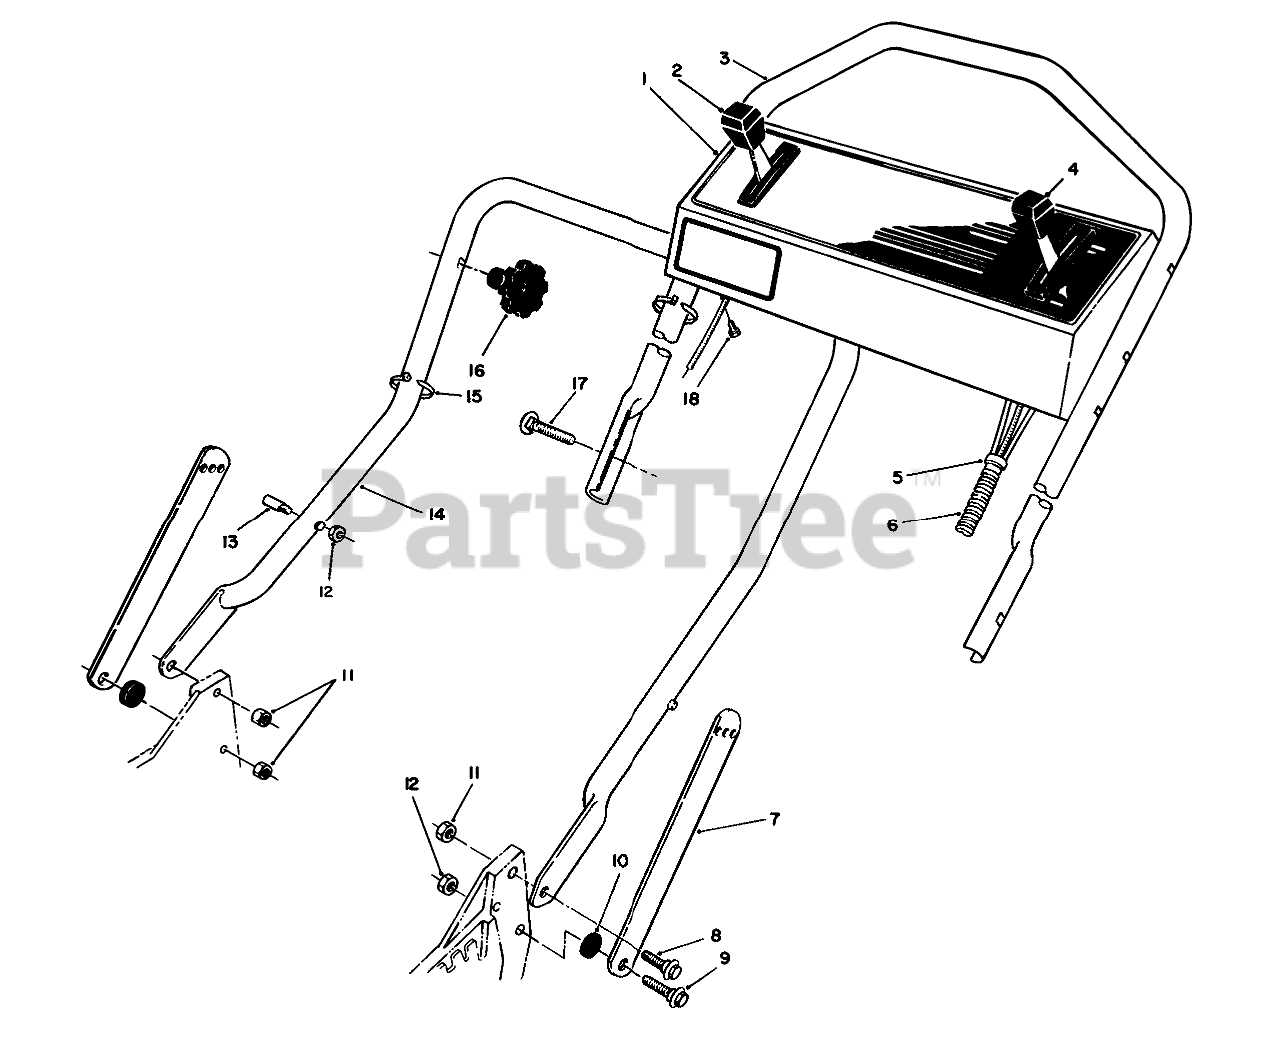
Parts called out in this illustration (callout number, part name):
1	SILK SCRN CONTROL PANEL
2	GROUND SPEED CONTROL
3	Handle-Upper
4	THROTTLE CONTROL
5	FITTING-RING
6	CONTROL CABLE COVER
7	Handle Latch
8	SCREW-SHOULDER
9	SCREW-SHOULDER
10	SPACER
11	NUT-LOCK, NI
12	NUT-LOCK, NI
13	HANDLE PIN
14	LOWER HANDLE ASM
15	TIE-CABLE
17	5/16-18 X 2 HNDLE SCREW
18	SCREW-HWHTF
